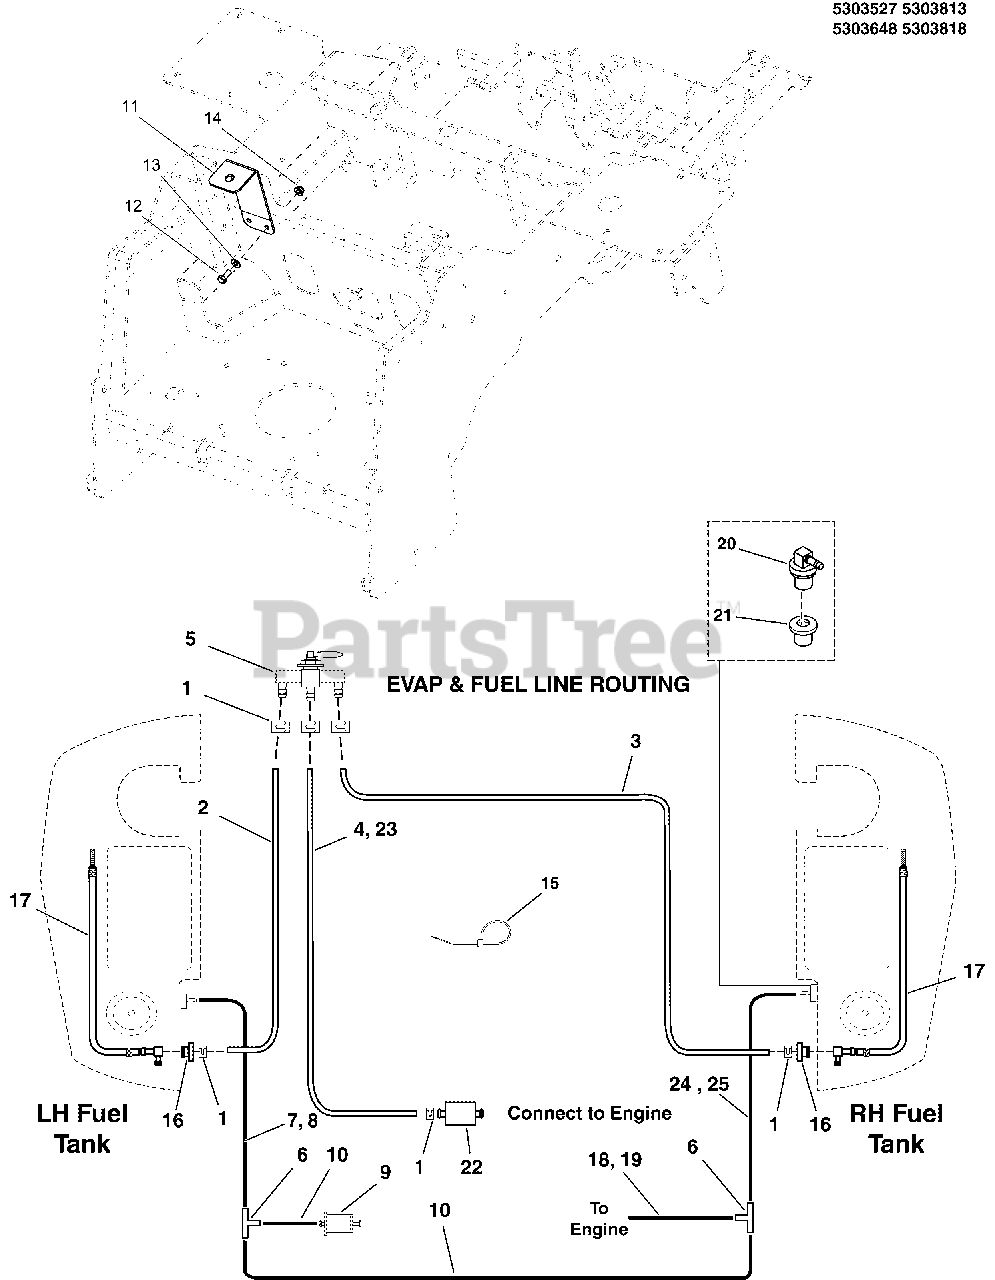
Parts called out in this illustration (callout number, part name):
1	CLAMP, HOSE, EXTERNAL, 1/2 - RED
2	HOSE, 1/4" FUEL, 11.00"
3	HOSE, 1/4" FUEL, 27.00"
4	HOSE, 1/4" FUEL, 19.50"
5	VALVE, FUEL SHUT-OFF, 11772
6	FITTING, 3/16" TEE, BARB TYPE, HDPE
7	HOSE, VAPOR, 5MM ID, 15.50 LG
8	HOSE, VAPOR, 5MM ID, 23.00 LG
9	FILTER, FUEL
10	HOSE, VAPOR, 5MM ID, 6.00 LG
11	BRACKET, FUEL VALVE, IS2100 - BLK
12	BOLT, 5/16-18 X 3/4 GD5
13	WASHER, 5/16 SAE
14	NUT, 5/16-18 HEX NYLOCK FLANGE
15	TIE,SELF-LOCKING, 6"
16	BUSHING-FUEL TANK RED RUBBER (SV)
17	HOSE ASSEMBLY (SV)
18	HOSE, VAPOR, 5MM ID, 13.50 LG
19	HOSE, VAPOR, 5MM ID, 16.00 LG
20	REMOTE, VENT ASSEMBLY, NO VALVE (SV)
21	GROMMET (SV)
22	FUEL FILTER (SV)
23	HOSE, 1/4" FUEL, 10.00"
24	HOSE, VAPOR, 5MM ID, 15.50 LG
25	HOSE, VAPOR, 5MM ID, 23.00 LG
